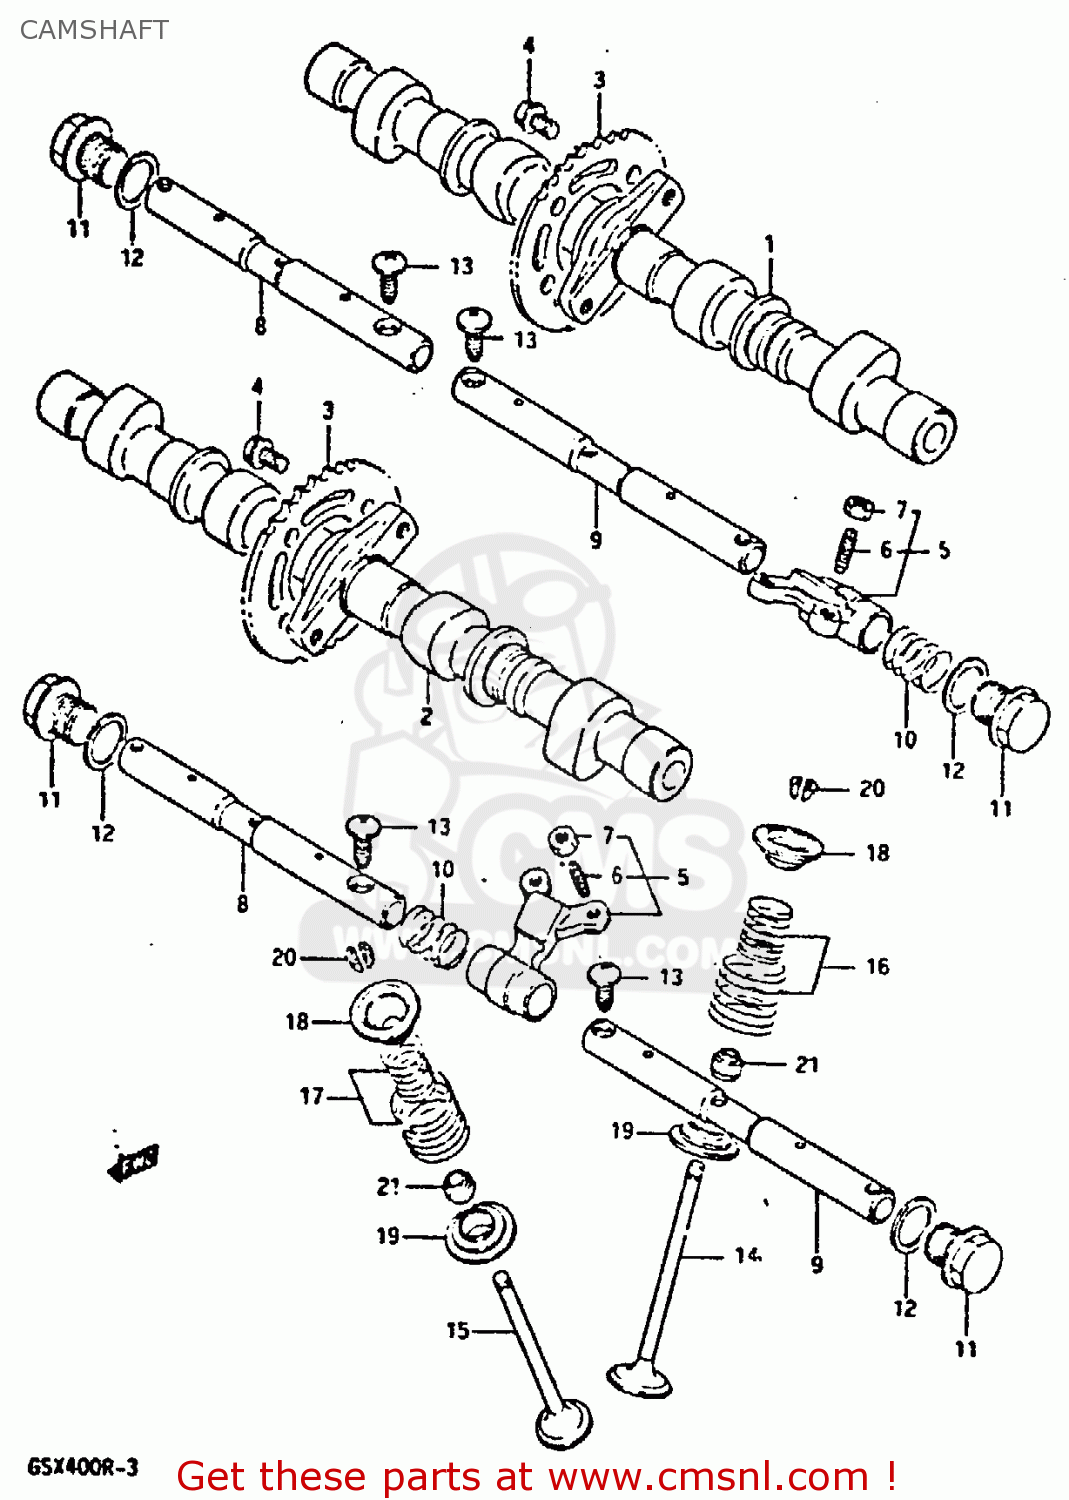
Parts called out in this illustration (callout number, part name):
1	INTAKE CAMSHAFT
2	NOKKENAS.UITL.
3	SPROCKET,CAMSHAFT
4	BOLT(7X11)
5	ROCKER
6	SCREW,TAPPET ADJUSTING
7	NUT,ADJUSTING
8	RH SHAFT
9	LH SHAFT
10	SPRING
11	PLUG,VALVE ROCKER ARM
12	GASKET(14X19.2X2) (NAS)
13	SCREW(6X16)
14	VALVE.INTAKE
15	UITLAATKLEP
16	SPRING SET,VALVE
17	SPRING SET,VALVE
18	RETAINER,VALVE SPRING
19	SEAT,VALVE SPRING
20	COTTER VALVE
21	SEAL,OIL(5X10.5X8.4)
